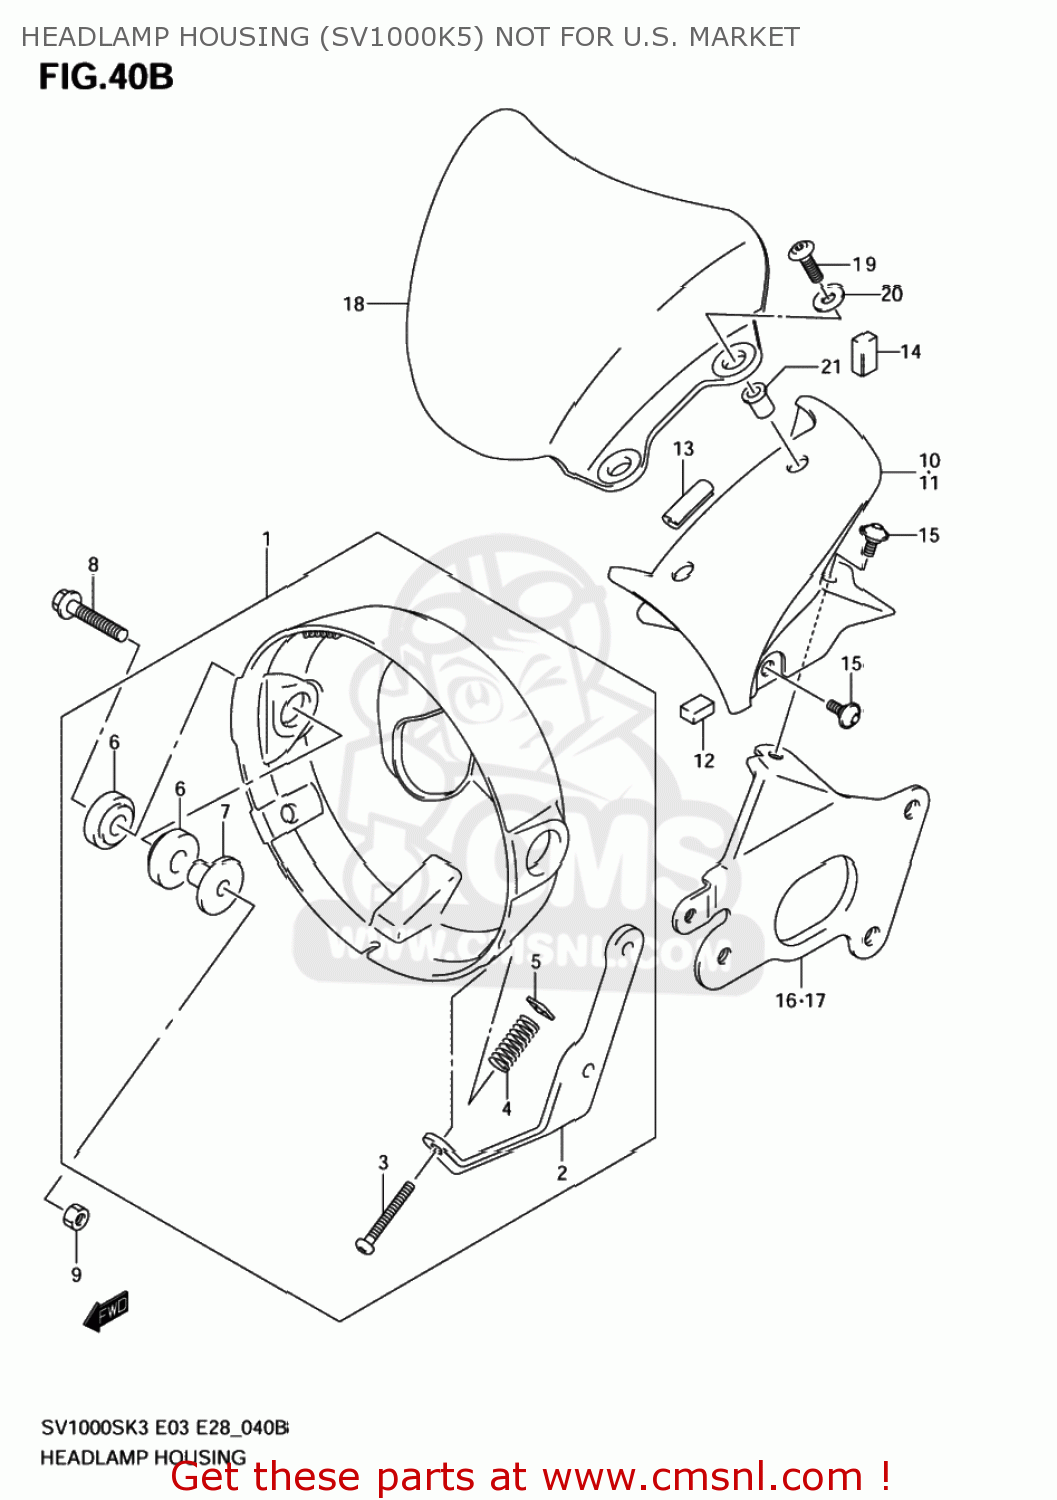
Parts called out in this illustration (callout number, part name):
1	HOUSING ASSY,HEADLAMP
2	PLATE,HEADLAMP HOUSING
3	SCREW(5X45)
4	SPRING,HEADLAMP ADJUSTER
5	NUT,HEADLAMP ADJUSTER
6	CUSHION
7	SPACER(8.6X12X21.3)
8	BOLT(8X35)
9	NUT
10	COVER,HEADLAMP HSG,R
11	COVER,HEADLAMP HSG,L
12	CUSHION,FR PANEL LID
13	MOLDING
14	TAPE
15	SCREW(5X13)
16	PLATE,HOUSING COVER,R
17	PLATE,HOUSING COVER,L
18	COVER,METER
19	SCREW(5X18)
20	WASHER
21	NUT
